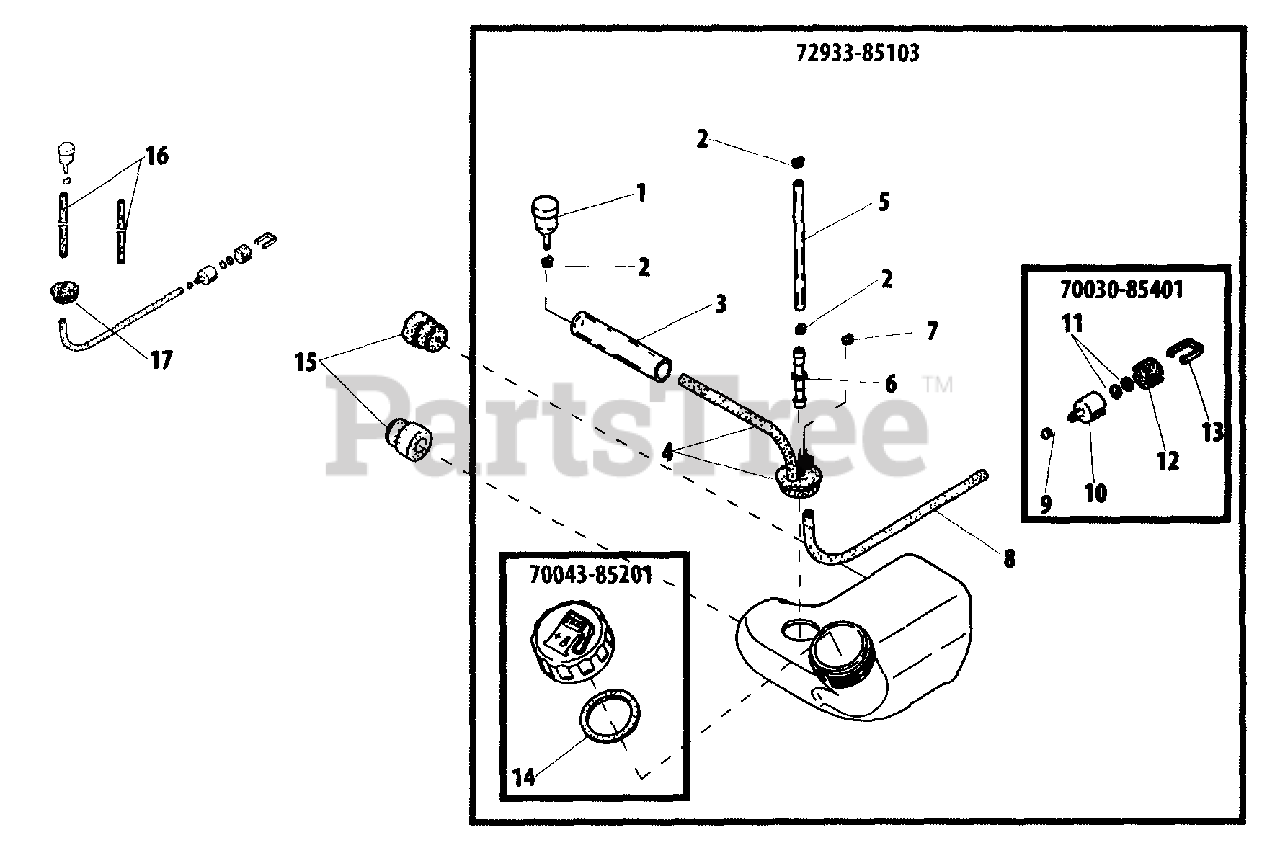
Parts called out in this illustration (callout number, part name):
1	CAP, BREATHER
2	RING, RETAINING - 6
3	VENT PIPE ASSY
4	PIPE ASSY
5	PIPE - FUEL
6	CONNECTOR, PIPE
7	CLIP
8	PIPE - FUEL
9	RING, RETAINING - 6
10	WEIGHT, FUEL FILTER
11	STRAINER - SMALL
12	ELEMENT, FILTER - LARGE
14	GASKET, CAP
15	CUSHION
16	TUBE
17	GROMMET
